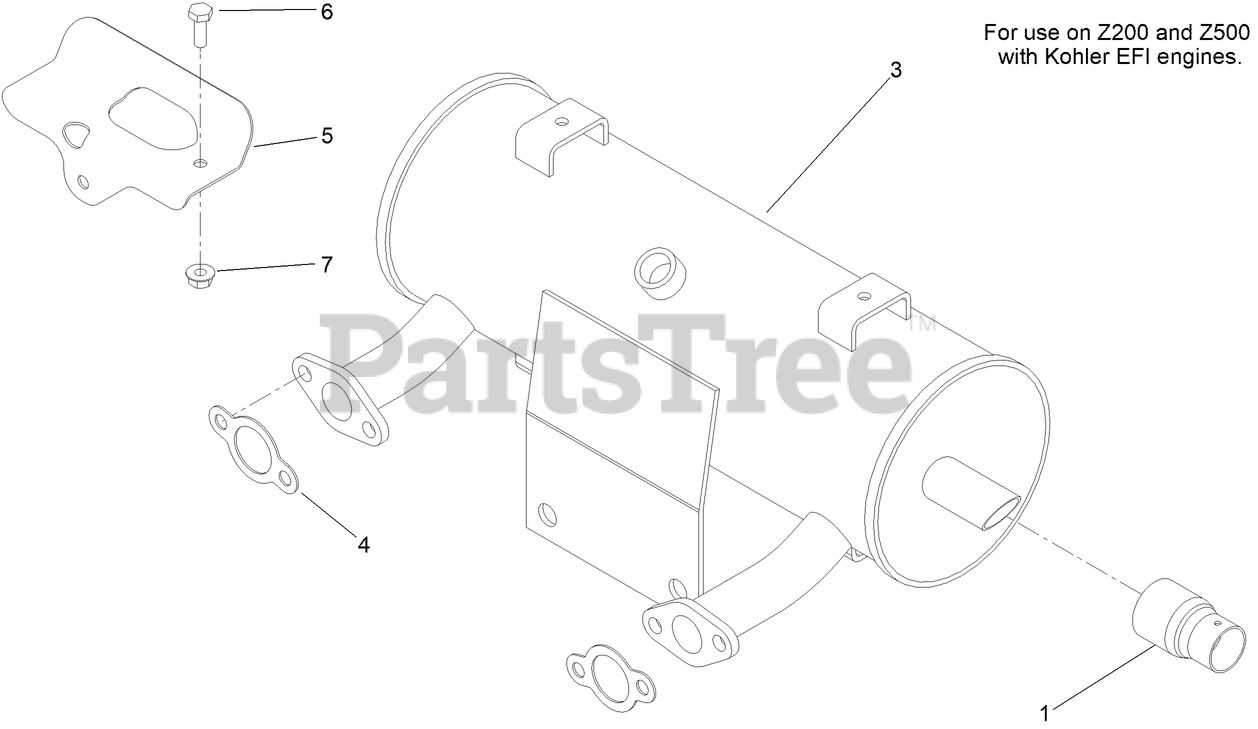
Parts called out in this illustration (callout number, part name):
1	SPARK ARRESTOR, 1.25 I.D.
3	MUFFLER
5	SHIELD-HEAT, CABLE
6	SCREW-HH
7	NUT-HF
